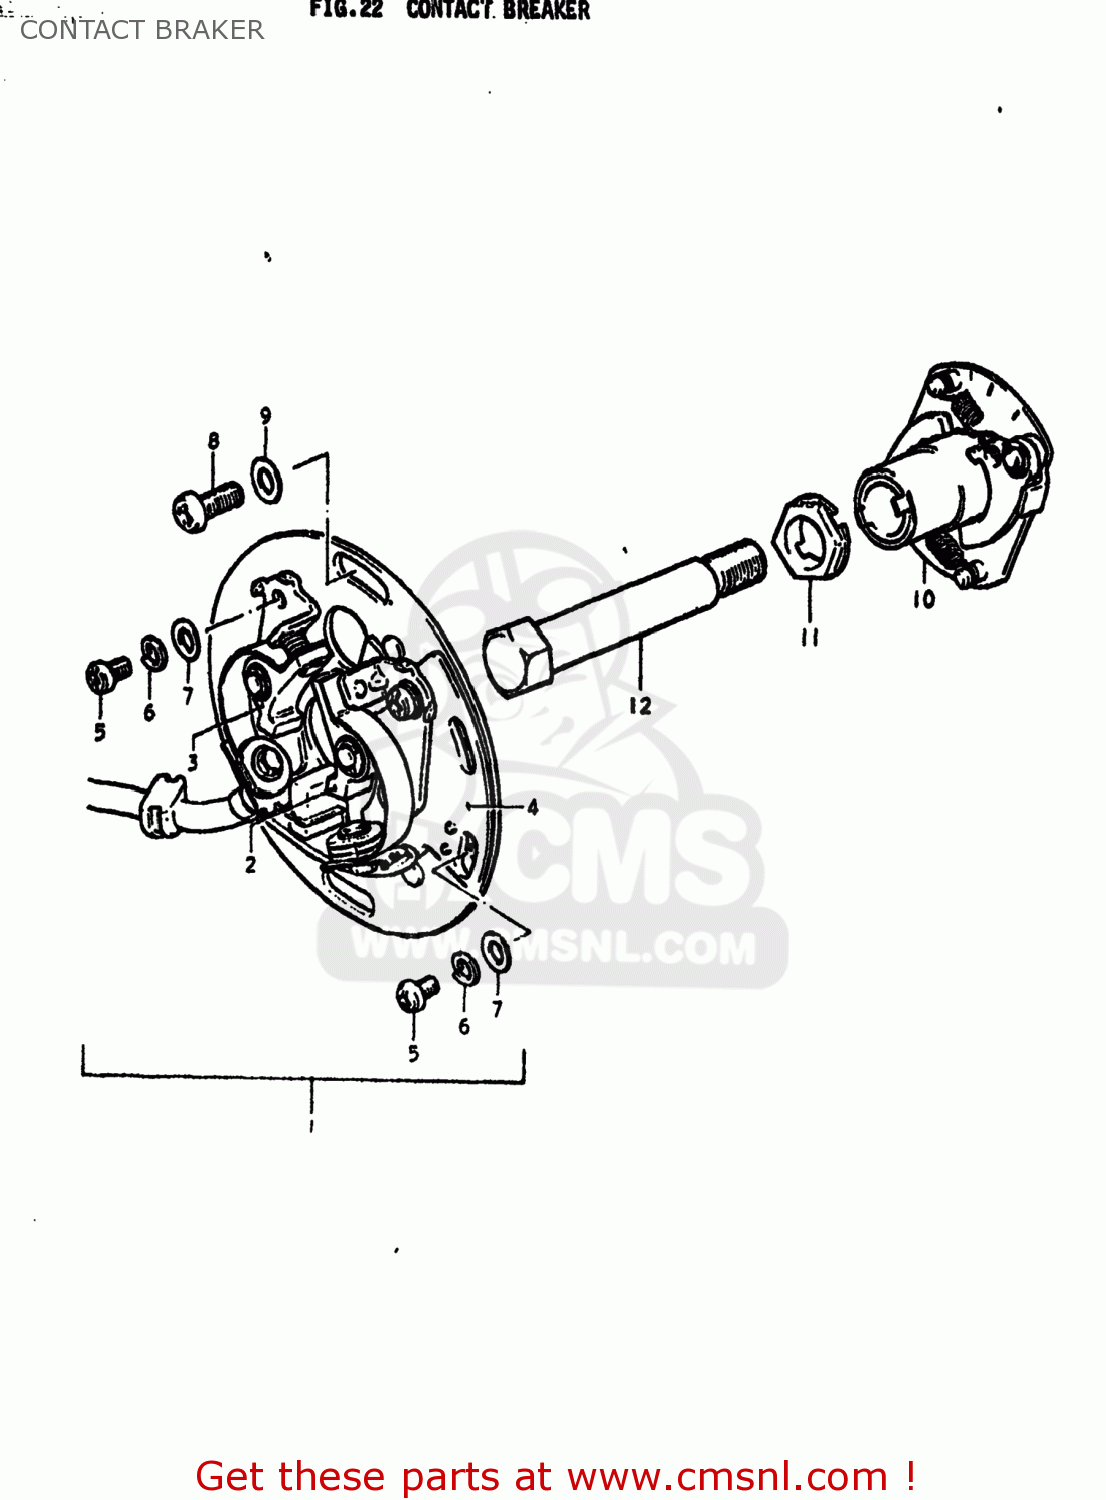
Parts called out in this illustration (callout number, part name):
1	SIGNAL GENERATOR ASSEMBLY
2	POINT ASSEMBLY,CONTACT
3	POINT ASSEMBLY,CONTACT
4	PLATE,CONTACT POINT
5	SCREW
6	LOCK WASHER
7	WASHER
8	SCREW(5X12)
9	WASHER 5MM
10	GOVERNOR ASSEMBLY
11	WASHER
12	BOLT
